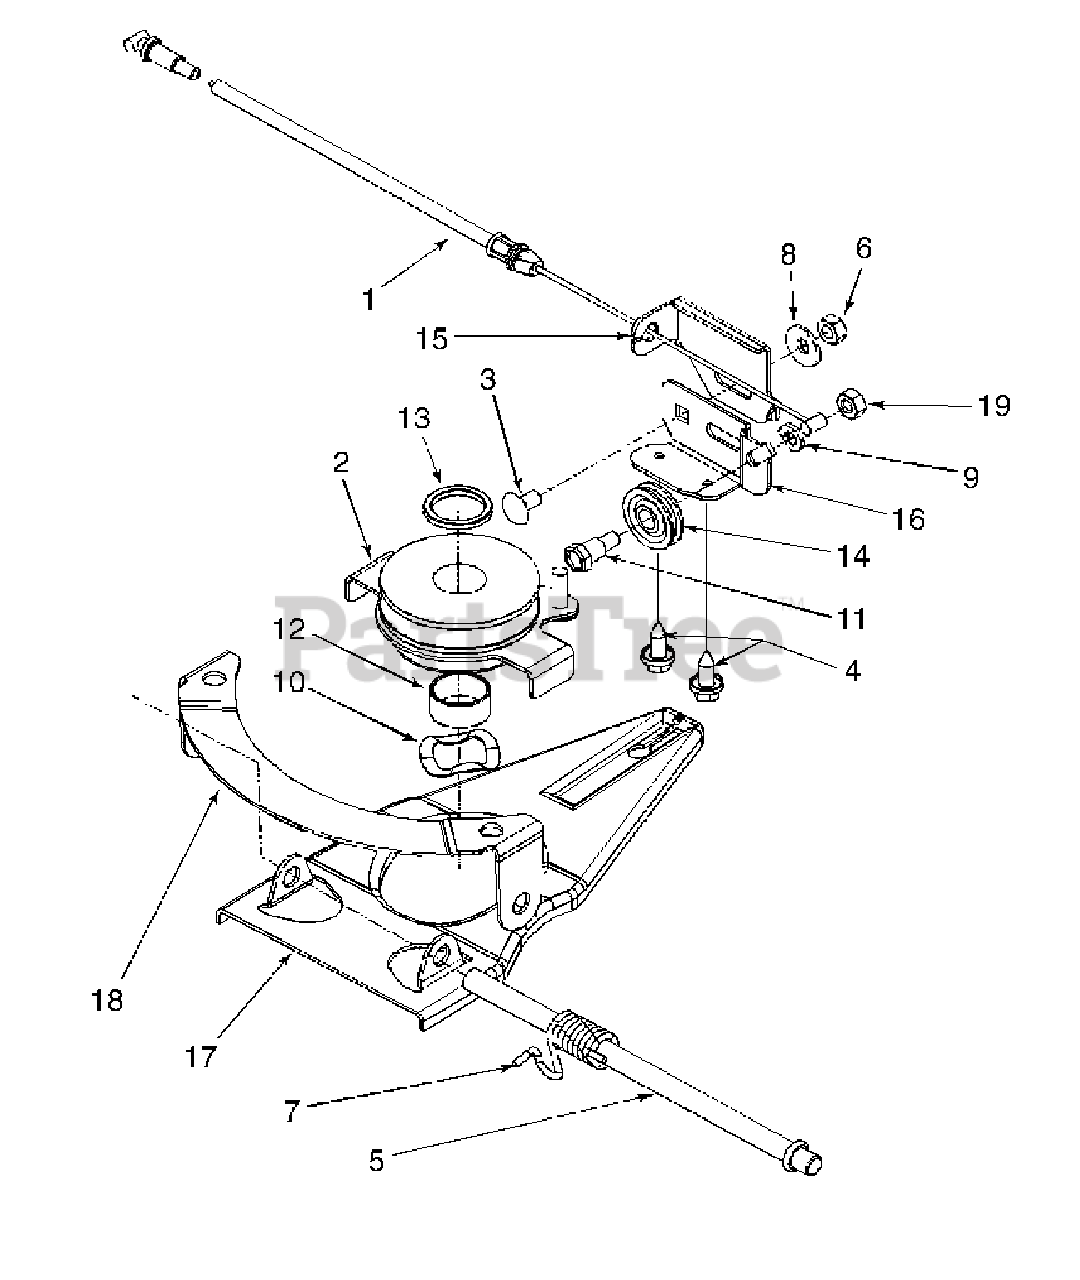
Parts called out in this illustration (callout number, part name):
1	6 Spd. Cable
2	Pulley Ass'y Mult - Spd.
3	Scr. 1/4-20 x .50 Carr.
4	Scr. AB 1/4-14 x .625 Hex hd. Wsh.
6	Nut 1/4-20
7	Torsion Spring LH
8	Bell Wash. .265 X .75 X .062
9	Lock Wash. 1/4 Reg Duty
10	Wave Wash. 1.38 x .88 x .029
11	Shld.Scr. .375 x 1/4 - 14AB
12	Slev Spcr. .88 ID 1.00 OD x .48
13	Slev Spcr .88 ID x 1.13 ID x .12
14	Roller Cable
15	6 Spd. Cable Adj. Bracket
16	6 Spd. Cable Mt. Bracket
19	Hex Nut 1/4-28
